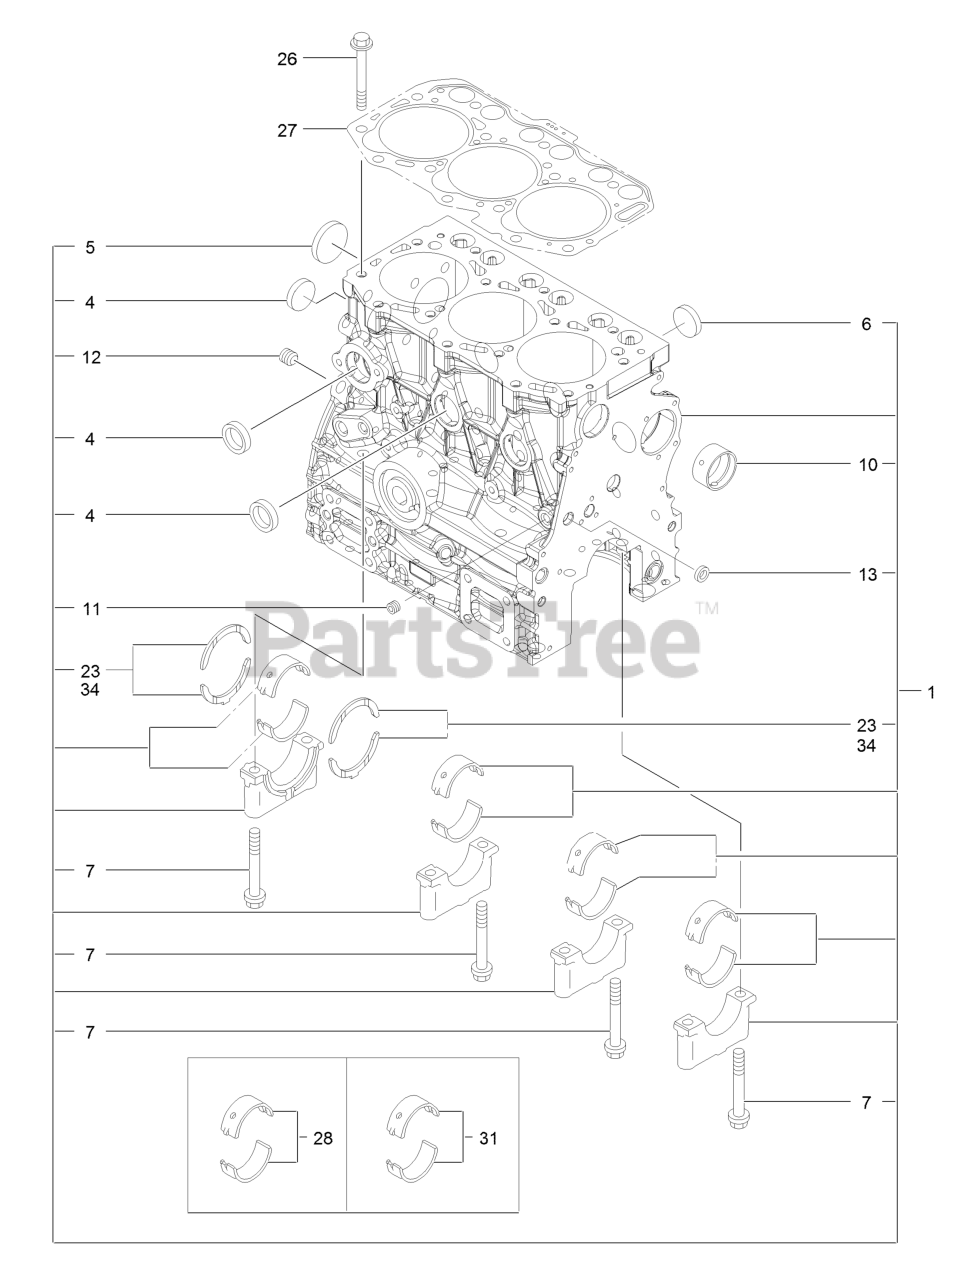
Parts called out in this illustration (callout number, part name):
1	Block ASM-Cylinder
4	Plug, Cup Type 30
5	Plug-Dish
6	Plug-Cup Type 25
7	Bolt-Metal Cap
10	Bush-Camshaft
23	Bearing Assy-Thrust
26	Bolt, Cylinder Head
27	Gasket Set-Head
28	Bearing Assy-Main
31	Bearing Assy-Main
34	Bearing-Thrust
